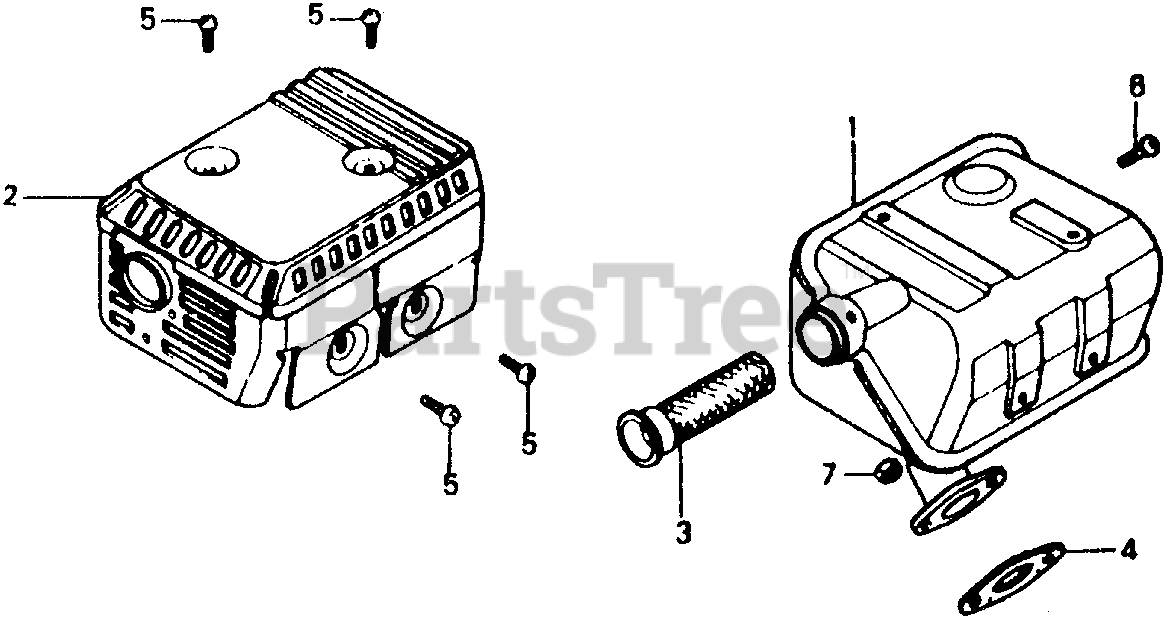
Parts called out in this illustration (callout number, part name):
1	MUFFLER (ARRESTER) Use up to Engine SN 1870782.
1	MUFFLER (ARRESTER) Use from Engine SN 1870783.
1	MUFFLER
2	PROTECTOR, MUFFLER
3	ARRESTER, SPARK
4	GASKET, MUFFLER
5	SCREW, TAPPING (5X8)
6	SCREW, TAPPING (4X6)
7	NUT, HEX. (8MM)
